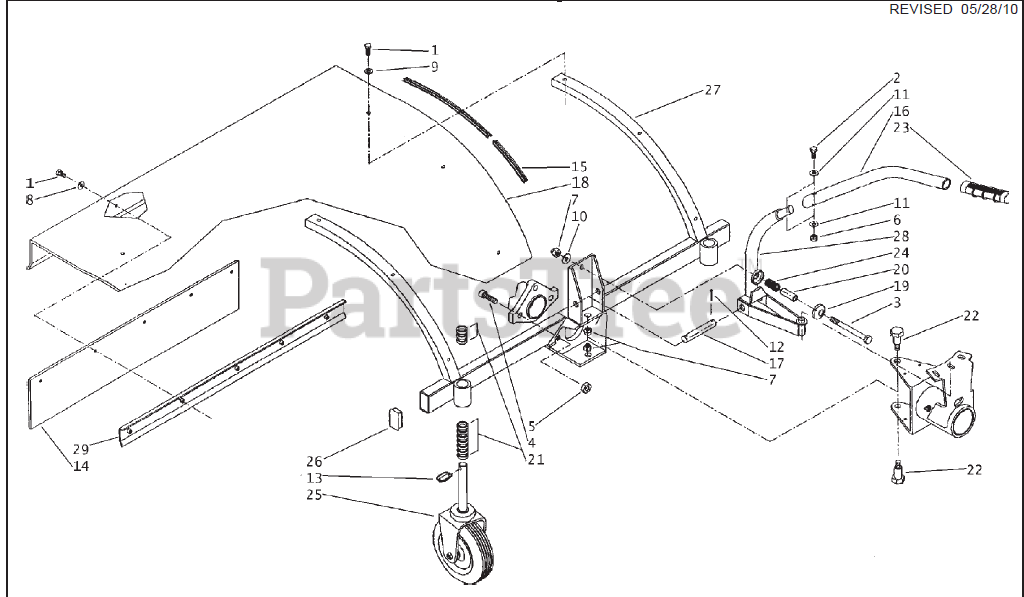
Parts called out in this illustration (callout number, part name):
1	CAPSCREW M6X16
2	CAPSCREW M8X40
3	CAPSCREW M10X120
4	SCREW M12X35
6	LOCKNUT M8 STANDARD
7	LOCKNUT M10 STANDARD
8	WASHER FLAT M6 4X12 5
9	WASHER FLAT M6 6X18
10	WASHER FLAT M10.5X18
11	WASHER LOCK B 8.4
12	PIN COTTER A 4X25 UNI 1336
13	RELEASE PIN
15	PROFILE, U 15MM
16	TUBE, POSITIONING
17	PIN, LEVER ADJUSTING
22	SPECIAL SCREW M10
24	SPRING, LEVER ORIENTATION
26	PLUG, FINNED
28	LEVER, ORIENTATION
29	RETAINER WITH ROLLER
